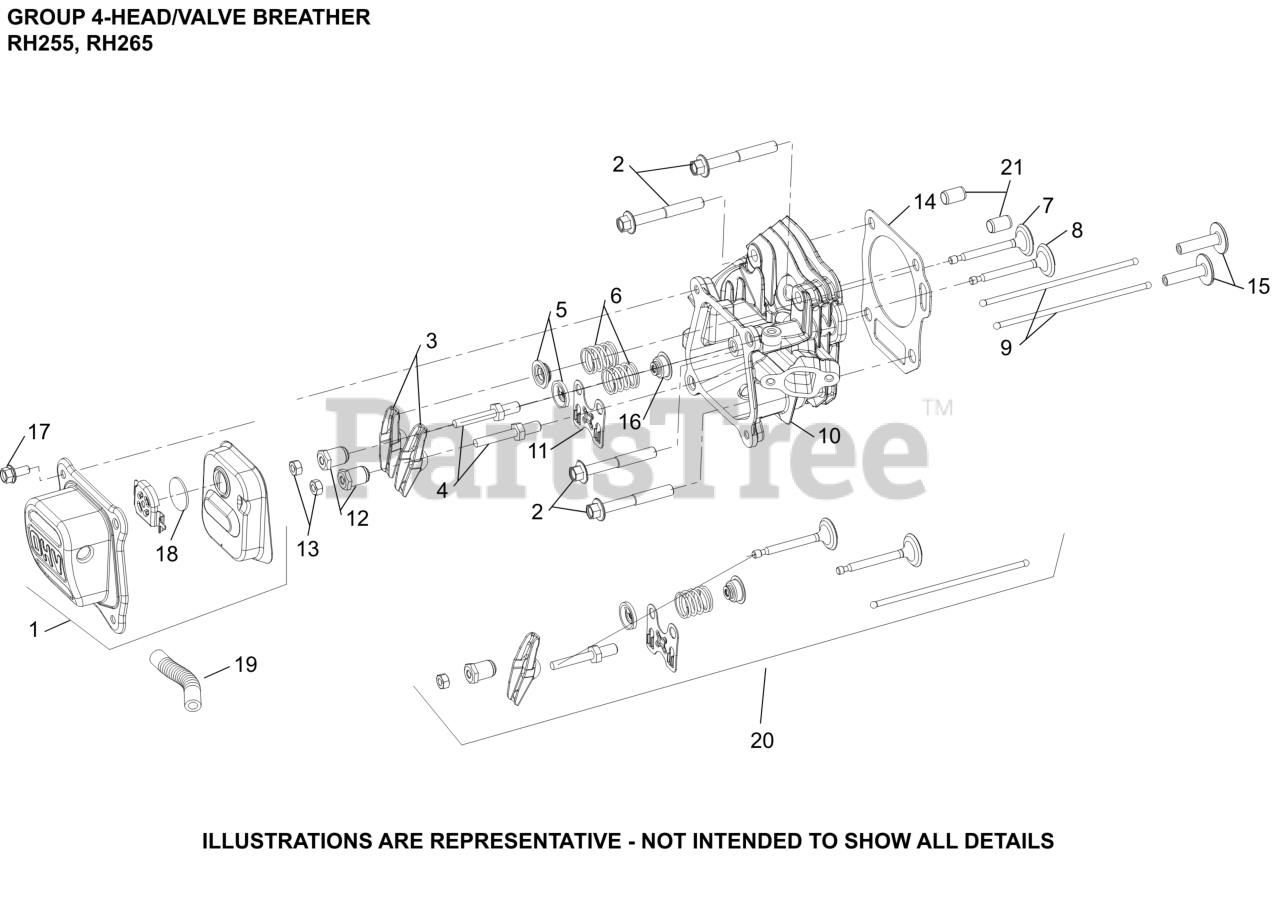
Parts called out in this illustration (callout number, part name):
1	COVER, VALVE ASSEMBLY
2	SCREW, HEX FLANGE CYL HEAD
3	ARM, ROCKER
4	STUD, ROCKER ARM-USE 14 072 22-S
5	RETAINER, VALVE SPRING
6	SPRING, VALVE
7	VALVE, EXHAUST
8	VALVE, INTAKE
9	ROD, PUSH-(#1841101S)
10	CYLINDER HEAD
11	PLATE, PUSHROD GUIDE
12	PIVOT, ROCKER ARM
13	NUT, HEX JAM
14	GASKET, CYLINDER HEAD
16	SEAL, VALVE
17	SCREW, HEX FLANGE (M6)-USE 25 086 433-S
18	REED, BREATHER
19	HOSE, BREATHER (LPAC)
20	KIT, VALVE TRAIN
21	DOWEL, CYLINDER HEAD
